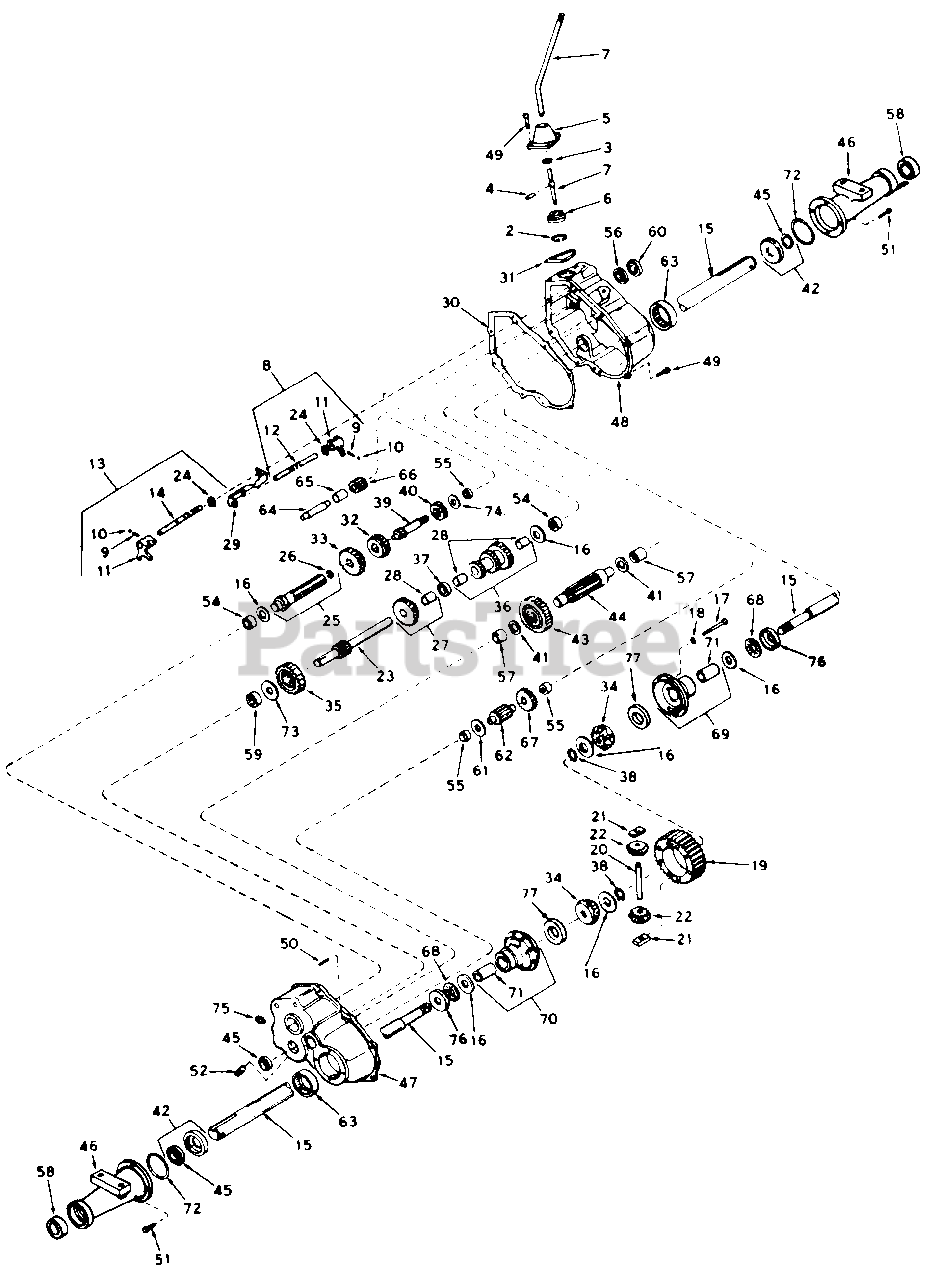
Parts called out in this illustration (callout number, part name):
2	Ring, Snap
3	Ring, Quad
4	Pin, Roll
5	Housing, Shift Lever
6	Keeper, Shift Lever
7	Lever, Shift
8	Rod Ass'y., Shift
9	Spring
10	Ball, Steel
11	Fork, Shifter
12	Rod, Shifter
13	Rod Ass'y., Shift
14	Rod, Shifter
15	Axle (18-11/32" Long)
16	Washer, Thrust
17	Scr., Hex Hd., 1/4-20 x 2-1/2
18	Lock Washer, 1/4"
19	Gear, Ring
20	Pin, Drive
21	Block, Drive
22	Pinion, Bevel
23	Shaft and Gear, Brake
24	Ring, Snap
25	Shaft and Bearing Ass'y., Pinion
26	Bearing, Needle
27	Gear Cluster Ass'y.
28	Bushing
29	Stop, Shifter
30	Gasket, Case and Cover
31	Gasket, Shifter Lever Housing
32	Gear, Shifting
33	Gear, Shifting
34	Gear, Bevel
35	Gear, Idler
36	Gear Cluster Ass'y.
37	Spacer
38	Ring, Snap
39	Shaft, Input
40	Spur Gear, Input Shaft
41	Washer, Thrust
42	Seal and Retainer Ass'y., Oil
43	Gear, Output
44	Pinion, Output
45	Seal, Oil
46	Housing, Axle
47	Cover Ass'y., Transaxle
48	Case Ass'y., Transaxle
49	Screw, Socket Hd., 1/4-20 x 314
50	Pin, Dowel
51	Screw, Hex Hd. Sems, 5/16-18 x 1
52	Plug, Magnetic Drain
54	Bearing, Needle
55	Bearing, Needle
56	Bearing, Ball
57	Bearing, Needle
58	Bearing, Ball
59	Bearing, Needle
60	Seal, Oil
61	Washer
62	Shaft and Pinion
63	Bearing, Needle
64	Shaft, Reverse Idler
65	Spacer, Reverse Idler
66	Idler, Reverse
67	Spur Gear (22 Teeth)
68	Bearing, Thrust
69	Carrier Ass'y., Differential
70	Carrier Ass'y, Differential
71	Bushing
72	"O" Ring
73	Washer, Thrust
74	Washer, Thrust
75	Plug, Pipe
76	Race, Thrust
77	Washer
